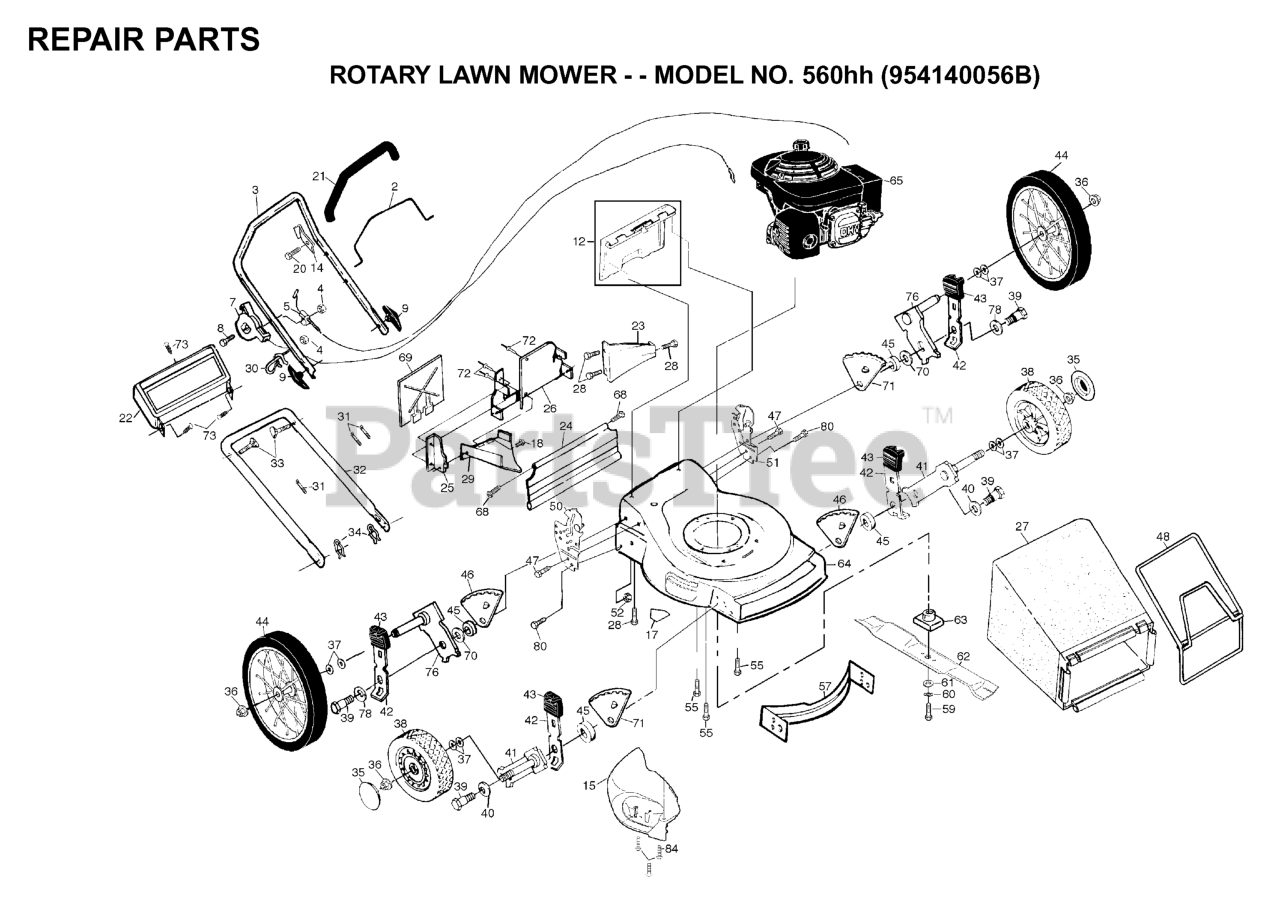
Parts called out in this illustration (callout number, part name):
2	CONTROL BAR/BLACK
4	NUT
5	CABLE.MZR.51.RT.SP./PU.
8	SCREW 1/4-20 X 2.12
9	HANDLE KNOB
14	BRACKET UPSTOP
17	DECAL HYT
18	SCREW.HXTAP.10-24
20	TAPPING SCREW
21	GRIP.HANDLE.FOAM
22	TRIM PLATE
23	REAR BAFFLE
24	REAR SKIRT
25	SIDE BAFFLE
26	BACK PLATE
27	GRASS BAG
29	DISCHARGE BAFFLE
30	ROPE GUIDE
31	TIE GUIDE
32	HANDLE, LOWER
33	HANDLE BOLT
34	HAIRPIN COTTER
35	HUBCAP.8".GREY
36	HEX FLANGE LOCKNT
37	WAVE WASHER
38	WHEEL.8X2.PR.LP.RAD.GREY
39	BOLT
40	WASHER.BELLEVILLE (3 2 LB)
41	AXLE ARM
42	SELECTOR SPRING
43	SELECTOR KNOB
44	WHEEL TIRE PM
45	RP SPACER HT ADJ
46	WHL ADJ BRKT LF/RR
47	SELF-TAPPING SCREW 5/16-18X3/4
48	CATCHER.FRAME.WALK
51	BRACKET
52	LOCKNUT PM
55	BOLT 3/8-16X1-1/8
57	BAFFLE
59	SCREW, HEX HD 3/8-24 X 1-3/8
60	LOCKWASHER
61	WASHER,HARDEN
63	BLADE ADAPTOR
68	HINGE SCREW
69	MULCHER PLATE
70	WASHER.FLAT.1/2
71	WHL ADJ BRKT RF/LR
72	RIVET BLIND
84	SCREW.PAN.HEAD.#10
